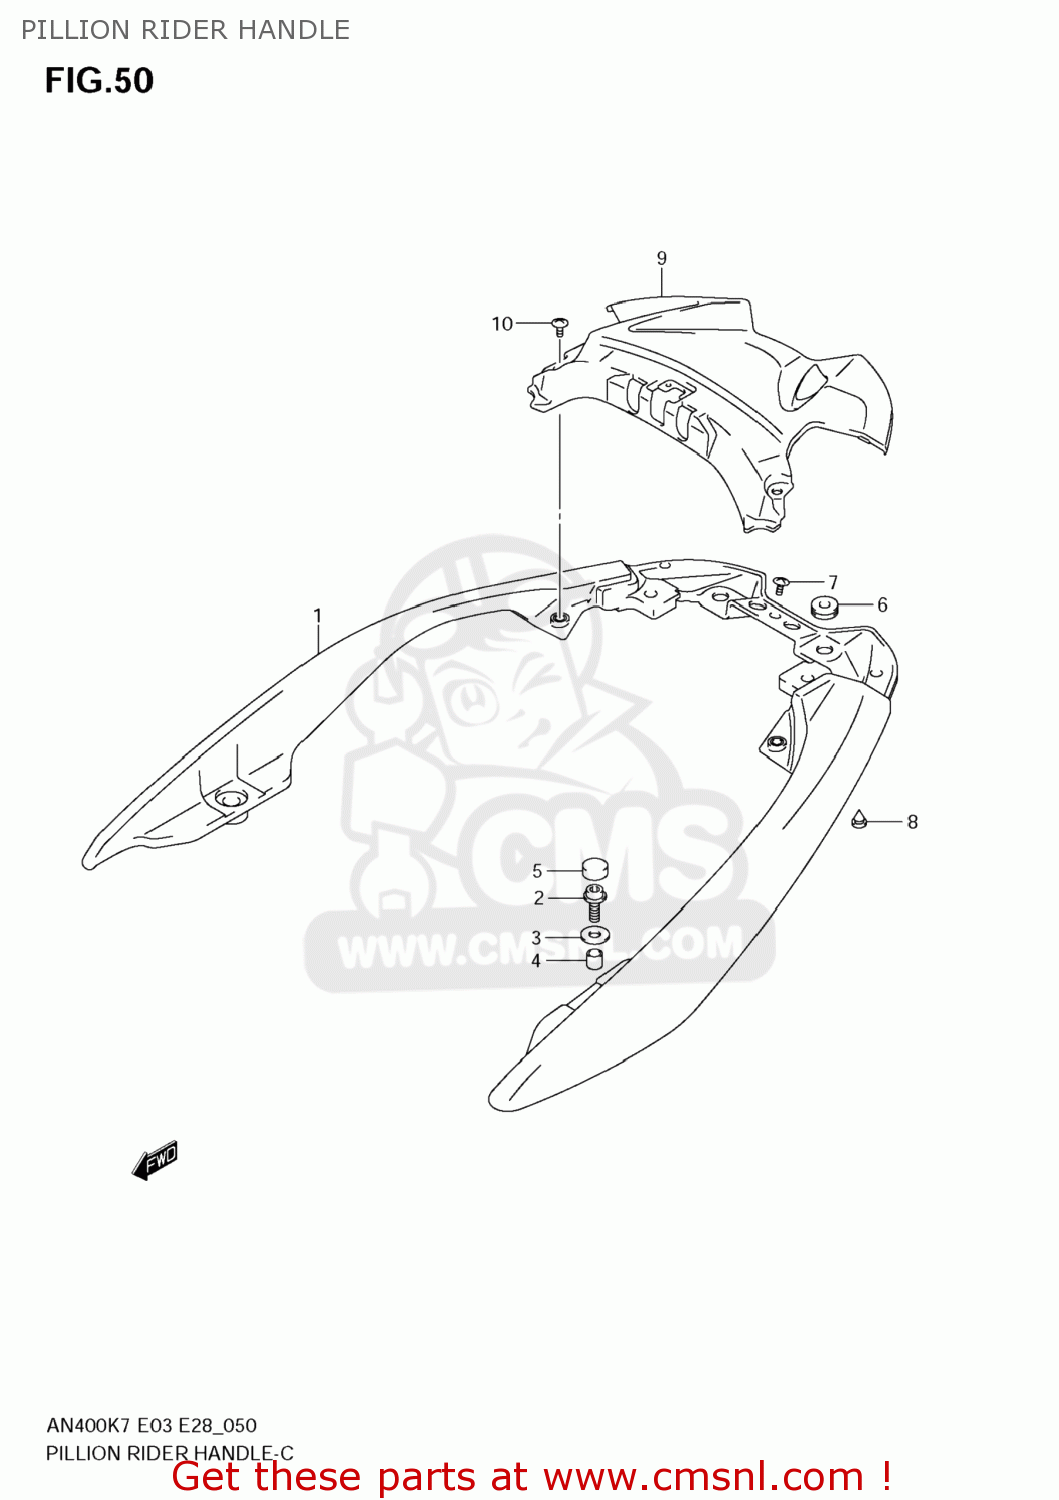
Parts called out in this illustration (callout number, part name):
1	HANDLE,PILLION
2	BOLT(8X25)
3	WASHER(8.5X22X2)
4	SPACER(8.4X12X13)
5	CAP
6	CUSHION
7	SCREW(6X16)
8	PLUG(OD:10)
9	COVER,PILLION HNDL FR
10	SCREW(6X16)
